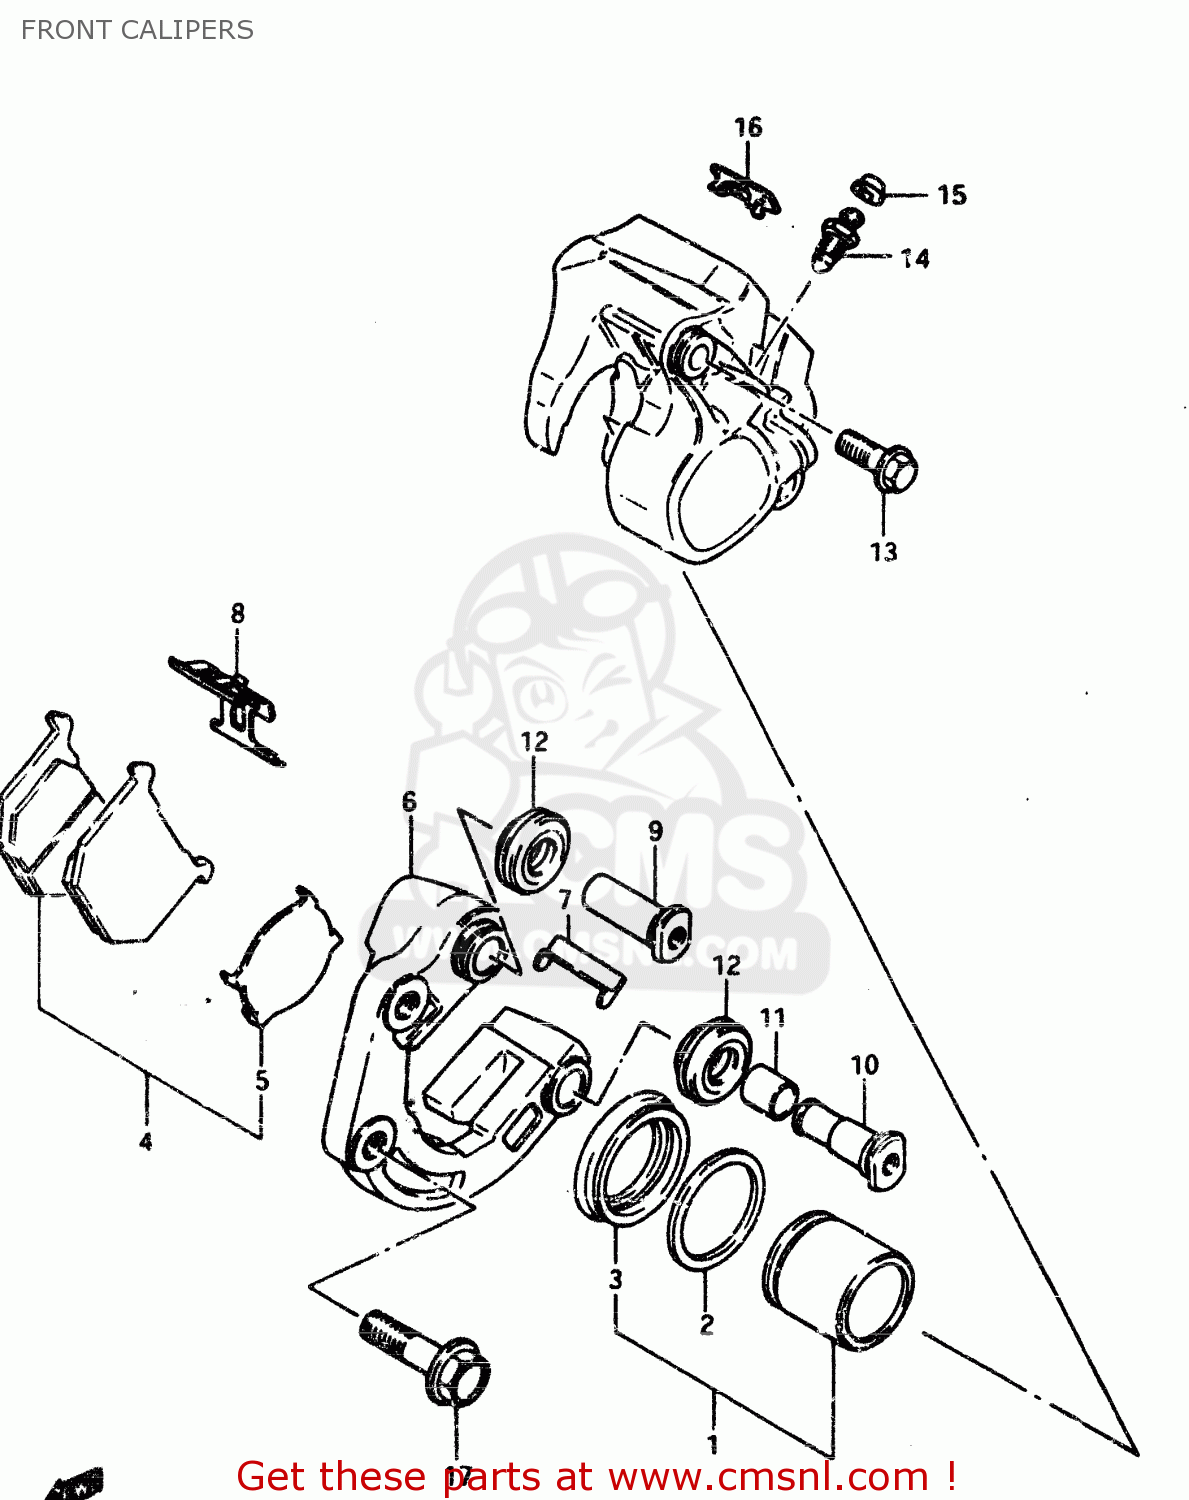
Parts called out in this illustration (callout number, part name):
1	PISTON SET
2	SEAL,FR CALIPE
3	BOOT,PISTON
4	PAD SET,BRAKE (MCA)
5	SHIM,PAD
6	CARRIER,CALIPER,LEFT
7	GUIDE,PAD
8	SPRING,PAD
9	AXLE NO.1
10	AXLE NO.2
11	BUSH,AXLE
12	BOOT,AXLE
13	BOLT
14	BLEEDER
15	CAP,BREATHER
16	COVER
17	BOLT(10X37)
